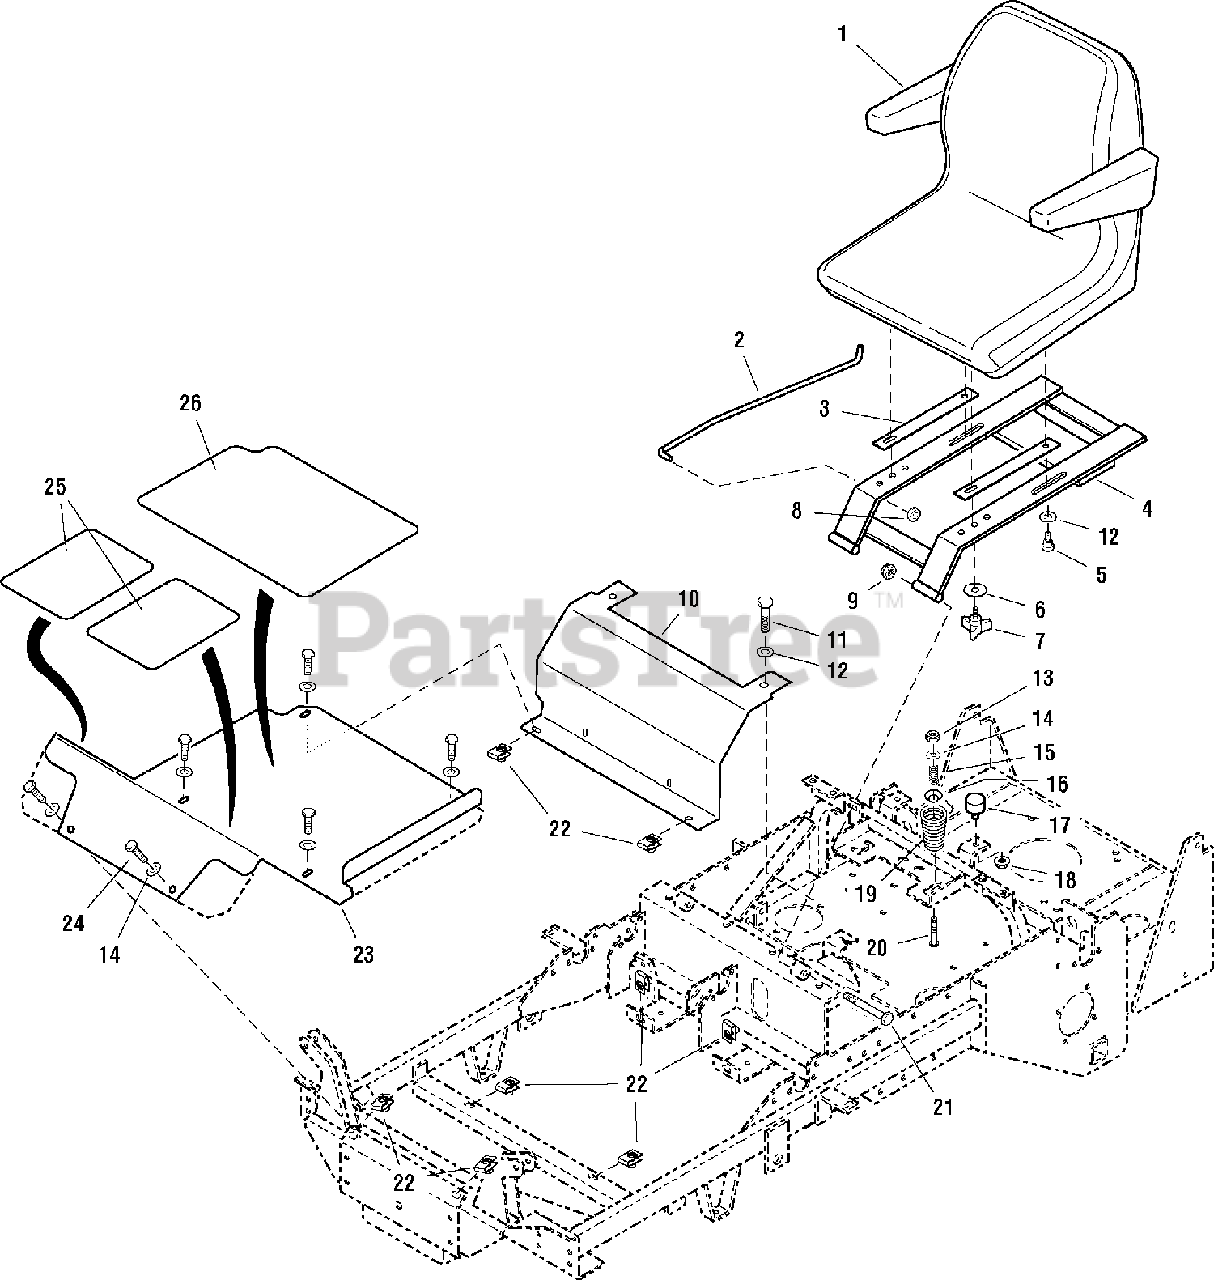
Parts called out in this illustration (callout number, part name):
1	SEAT
2	SEAT STOP ROD
3	PLATE, SEAT SLIDER
4	SEAT MOUNT
5	SHOULDER BOLT, 3/8 X 3/8
6	WASHER, USS, 5/16
7	KNOB
8	COLLAR, SET, 5/16
9	NUT, HEX NYLON LOCK, 3/8-16
10	BRAKE COVER PLATE
11	BOLT, 3/8-16 X 2, GD5, CZ
12	WASHER, SAE, 3/8
13	NUT, HEX NYLON LOCK, 5/16-18
14	WASHER, SAE, 5/16
15	SPRING, COMPRESSION
16	WASHER, SPRING, 5/16 X 1-1/4
17	BUMPER
18	NUT, HEX SERRATED FLANGE, 1/4-20
19	SPRING, COMPRESSION
20	CARRIAGE BOLT, 5/16-18 X 2
21	BOLT, 3/8-16 X 4" GD5 CZ
22	BODY CLIP, 5/16-18
23	FLOOR PLATE
24	BOLT, 5/16-18 X 3/4 GD5
25	SAFETY WALK
26	SAFETY WALK
